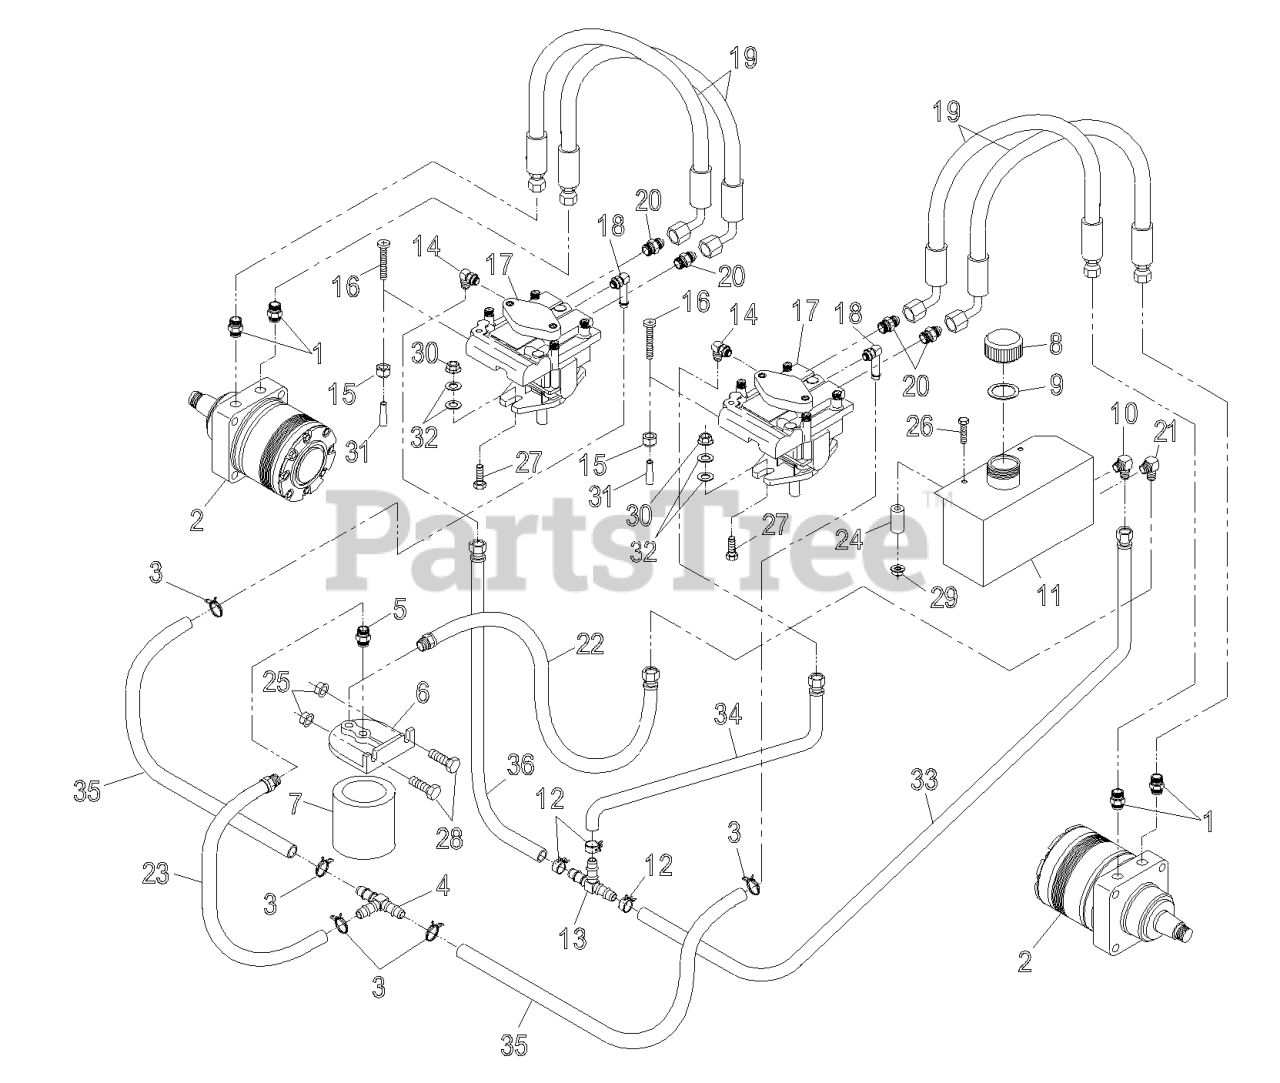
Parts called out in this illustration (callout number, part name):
1	FITTING-STRAIGHT
2	HYD MOTOR ASM
3	CLAMP-HOSE
4	FITTING-TEE, HOSE
5	FITTING-STRAIGHT
9	GASKET-CAP, TANK
10	FITTING-ELBOW
12	CLAMP-HOSE
13	FITTING-TEE, HOSE
14	FITTING-90 DEG
18	FITTING
19	HOSE-PRESSURE, HIGH
20	FITTING-STRAIGHT
21	FITTING-ELBOW
22	ASM,HOSE LO PRESSURE
23	ASM,HOSE CHARGE LINE
31	GRIP-VALVE, DUMP
33	ASM,HOSE CASE DRAIN
34	HOSE ASM
36	HOSE ASM
